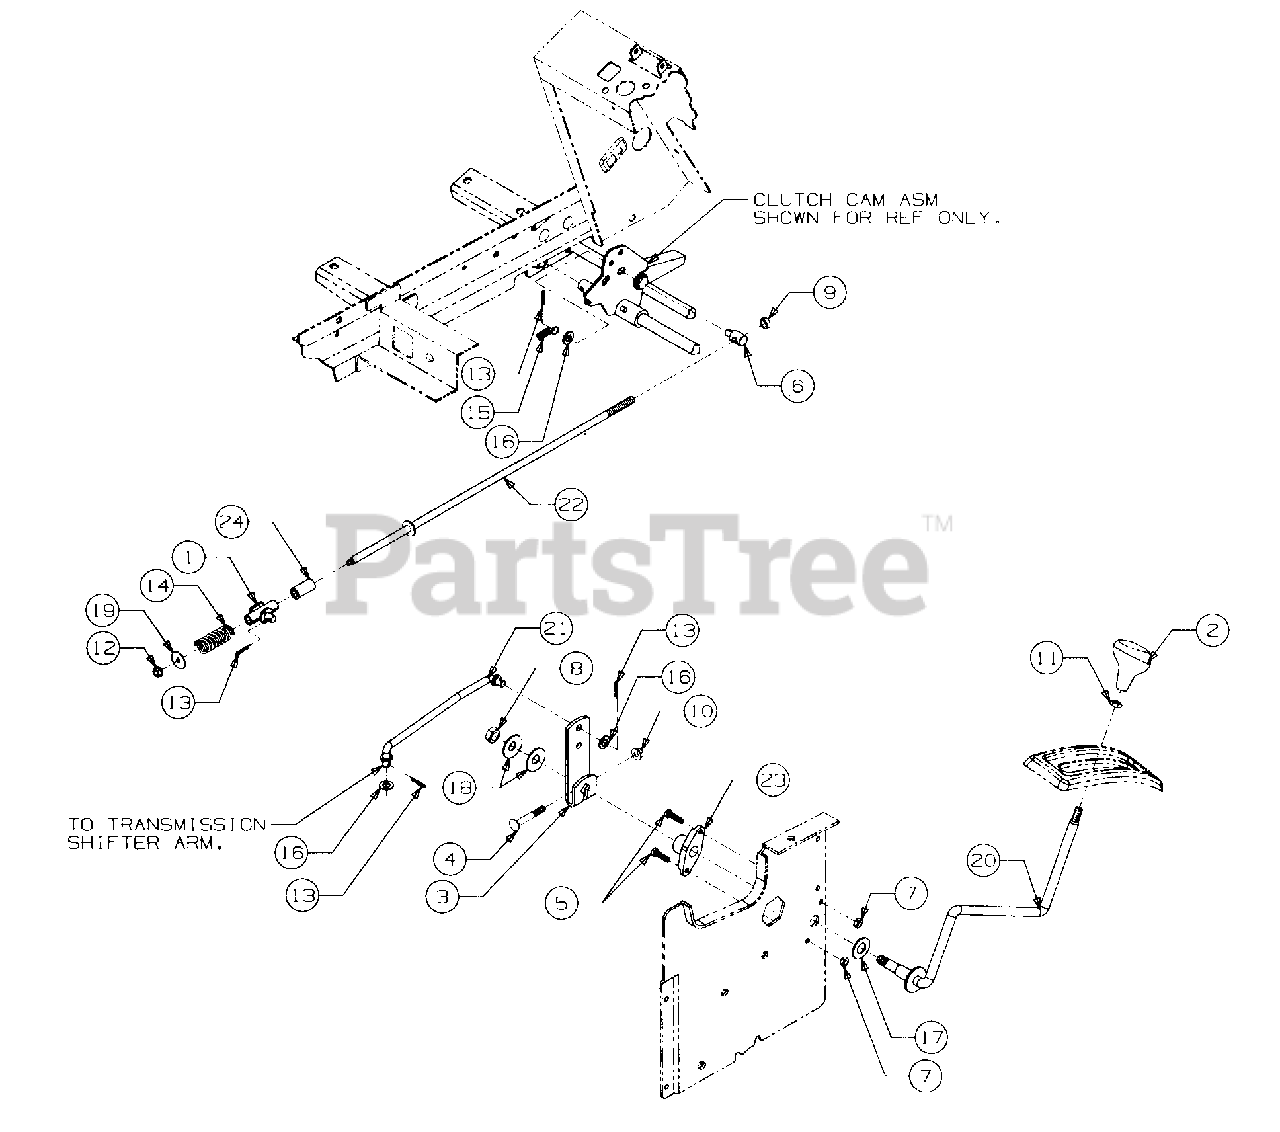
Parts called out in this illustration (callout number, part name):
1	Pivot Assy, Sleeve
2	Knob, Shifter
3	Bracket, Gear Shift
4	Bolt, Carriage, 5/16-18 x 2.25 Lg GR5
5	Screw, Hex Cap, 1/4-20 x 1.0 Lg
6	Ferrule, Adjustment
7	Nut, Hex Sems, 1/4-20
8	Nut, Hex Jam Lock, 1/2-20
9	Nut, Hex Jam, 3/8-24 GR5
10	Nut, Hex Flange Top Lock 5/16-18
11	Nut, Hex Jam, 3/8-16 GR5
12	Nut, Hex Flange Lock, 1/4-20
13	Pin, Internal Cotter, 5/16 Dia x 1.12 Lg
14	Spring, Compression, .63 ID x 2.0 Lg
15	Spring , Extension, .38 OD x 1.44 Lg
16	Washer, Flat, .406 x.75 x .063 Thk
17	Washer, Flat, .64 x 1.25 x .100 Thk
18	Washer, Bell
19	Washer, Flat, .265 x 1.0 x .030 Thk Hdn
20	Lever, Speed Control
21	Rod, Gear Shift
22	Rod, Clutch Adjustment
23	Bushing, Control Lever
24	Spacer, .39 ID x .63 OD x 1.25 Lg
